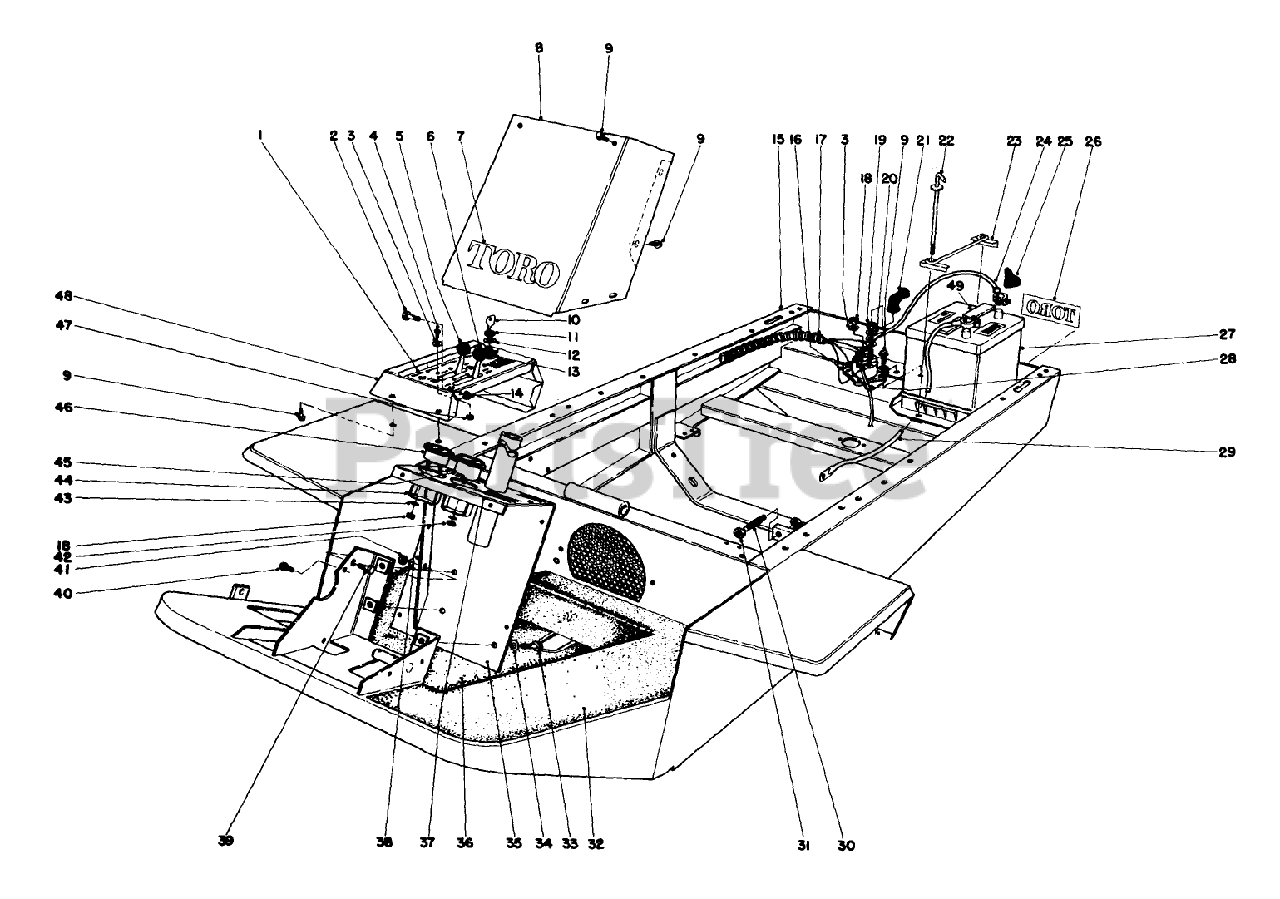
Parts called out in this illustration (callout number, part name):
1	Decal-Instrument Panel
2	SCREW-HH
3	WASHER-LOCK
4	10-24 X 5/8 PAN HD MS
5	CHOKE CONTROL
6	Throttle Control
7	DECAL
8	Cover-Tower
9	SCREW-THD FRM,HWH
10	Key
11	NUT-HH
12	WASHER-TOOTH, INTERNAL
13	SWITCH-STARTER
14	NUT-HEX
15	Frame
16	SOLENOID
17	Wire Harness
18	NUT-HEX
19	NUT-JAM, BRASS
20	Lockwasher
21	BATTERY BOOT
22	BATTERY BOLT WA B
23	BATTERY HOLD DOWN WA
24	Wire Positive Batter to Solenoid
25	BOOT-CABLE, BATTERY
26	DECAL
27	Battery
28	SOLENOID TO START WIR
29	BATTERY GROUND WIRE
30	STOP PIN PP
31	NUT-JAM
32	NON SKID (TUNNEL)
33	SCREW-HH
34	WASHER-LOCK
35	Steering Post
36	NON-SKID-FLOOR
37	Decal Instruction
38	WASHER-LOCK
39	SCREW-HH
40	SCREW-HWH
41	NUT-HEX
42	NUT-HEX
43	WASHER-LOCK, INT
44	CLAMP ASM
45	HOUR METER
46	Ammeter
47	NUT-HEX
48	Instrument Panel
49	PUSH-ON BATTERY CAP
